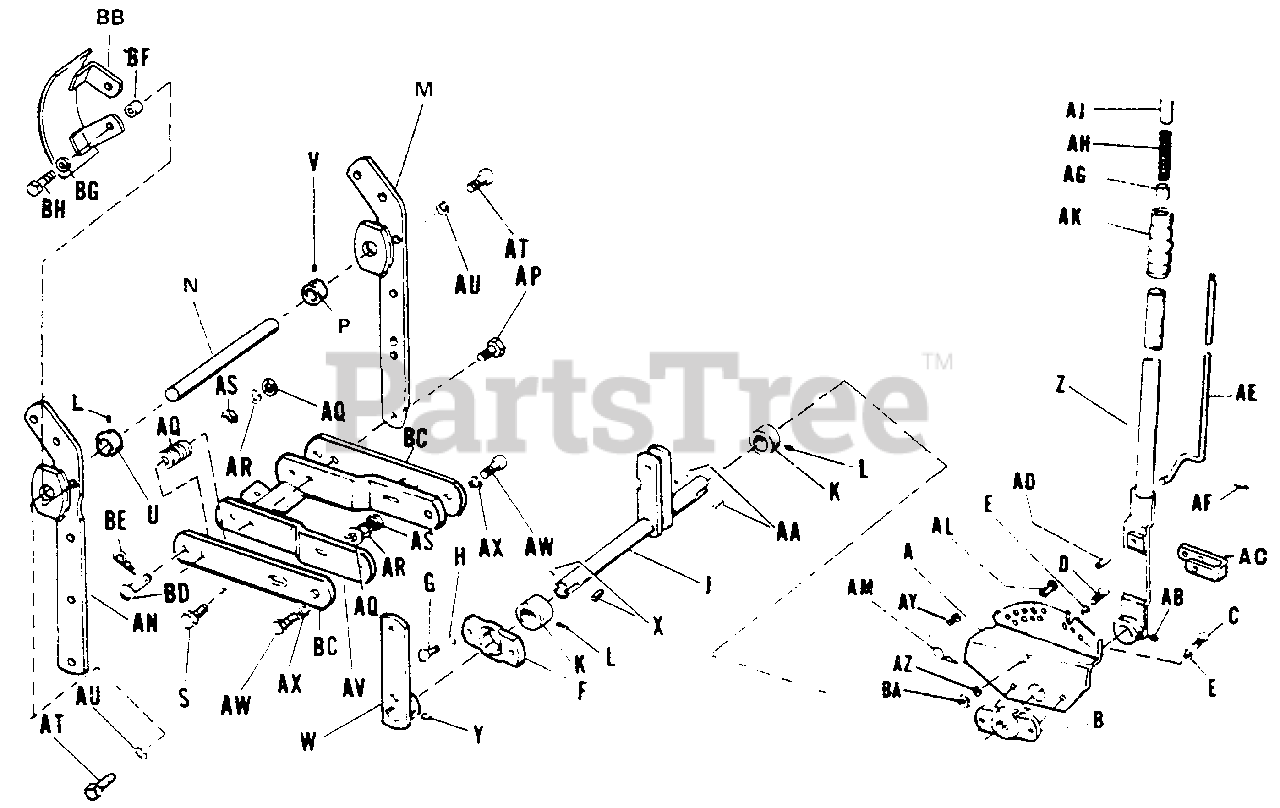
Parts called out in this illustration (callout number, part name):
A	Lift Lever Quadrant
B	Lift Lever Bearing
C	Hex. Cap Screw, 3/8" 16 x 7/8"
D	Hex Cap Screw, 3/8"-16 x 1 1/4"
E	Lock Washer, 3/8"
F	Lift Lever Bearing
G	Hex. Cap Screw, 3/8"-16 x 7/8"
H	Lock Washer, 3/8"
J	Lift Shaft Assembly
K	Set Collar
L	Set Screw, 5/16" 18 x 5/16"
M	Arm Assembly
S	Hex. Cap Screw, 7/16"-14 x 1 3/4"
U	Set Collar
V	Set Screw, 5/16" 18 x 1/2"
W	Front Lift Lever Assembly
Y	Set Screw,
Z	Lift Lever Assembly
AB	Set Screw, 5/16"-18 x 1/4"
AC	Lift Lever Latch
AE	Latch Rod
AF	Cotter Pin 3/32" x 3/4"
AJ	Thumb Button
AK	Handle Grip
AM	Spring Clip
AN	Arm Assembly
AP	Hex Cap Screw 7/16"-14 x 1 1/2"
AQ	Plain Washer, 3/8"
AR	Lock Washer
AS	Full Hex Nut, 7/16"
AT	Hex. Cap Screw, 7/16" 14 x 1"
AU	Lock Washer, 7/16"
AV	Draw Bar Assembly
AW	Hex. Cap Screw, 7/16-14 x 1"
AX	Lock Washer, 7/16"
AY	Hex. Cap Screw, 1/4"-20 x 5/8"
AZ	Lock Washer, 1/4"
BA	Hex Nut 1/4-20
BB	Pulley Guard Assembly
BD	Round Head Pin
BE	Spring Clip
BG	Lock Washer 7/16"
BH	Hex Cap Screw, 7/16" 14 x 1 1/2"
